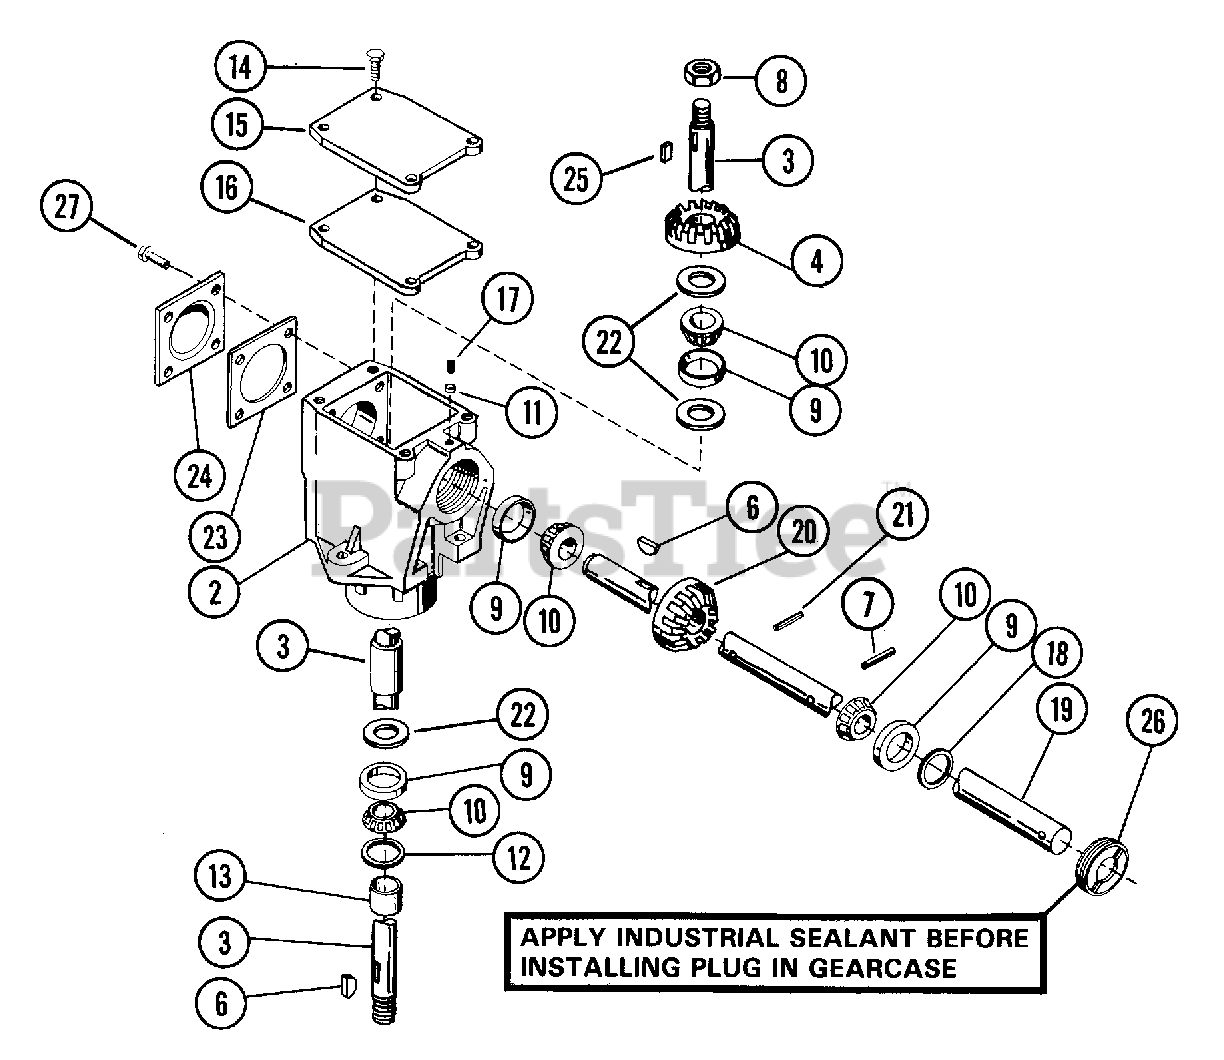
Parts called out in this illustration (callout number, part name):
1	MOWER GEAR CASE OLD 48" & 60"
1	MOWER GEAR CASE 42" AND NEW 48
2	GEAR CASE
3	OUTPUT SHAFT
4	GEAR
4	GEAR - BEVEL
6	KEY-WDRF .25X.750X.313 SAE91
7	@PIN-GRV .188X1.25 TP E ALLOY
8	NUT-JAM-CTR .562-18 PLAIN
9	BRG-CUP 1.781X.475
10	BRG-CONE .750X.61
12	SEAL 1.000X1.980X.375
13	SPACER .752X1.000X.850
14	SCR-TAP 8-32X.38 SL HWH PL 23
15	COVER, GEAR CASE
16	TOP GASKET
17	SCR-SET .25-20X.25 SKHCUPNY OH
18	SEAL .750X1.499X.225
19	SHAFT, INPUT
20	GEAR - BEVEL
21	PIN-GRV .188X1.00 TP E
22	WSHR-FL-STL .781X1.000X.025
22	WSHR-FL-STL .781X.1.000X.005
22	WSHR-FL-STL .781X1.000X.003
22	WSHR-FL-STL .754X1.000X.032
22	WSHR-FL-STL .781X1.000X.015
23	GASKET - SHIM KIT
23	SIDE COVER GASKET
24	BEARING SIDE COVER
25	KEY-SQ .25X.625X.25 SAE 8630
26	ADJUSTMENT PLUG
27	SCR-TAP .312-18X.75 HWH PL TR
28	MULTIPURPOSE GREASE
